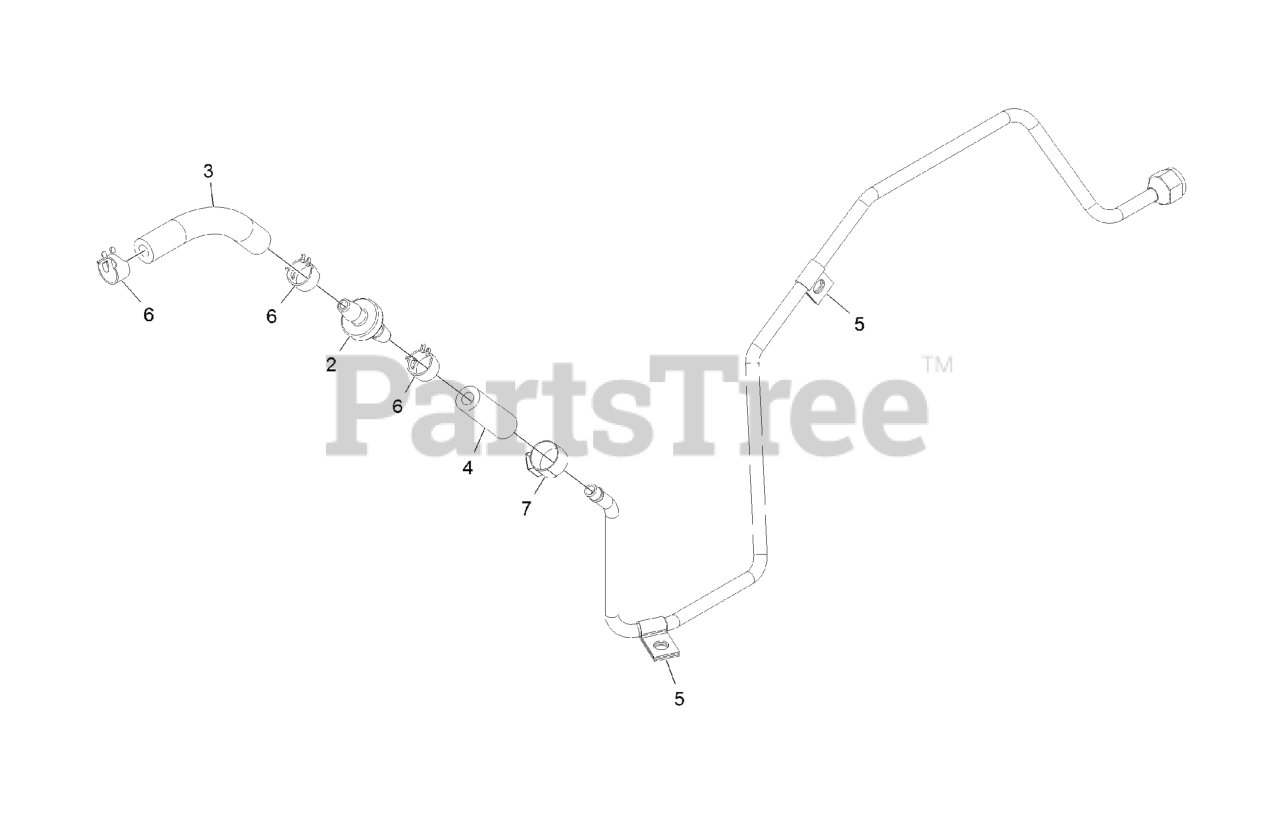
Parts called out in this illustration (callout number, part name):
2	VALVE-CHECK, FUEL
3	HOSE-FUEL
4	Hose-Fuel
5	CLIP-CLOSED, INSULATED
6	CLAMP-HOSE
7	Clamp-Hose, Fuel
